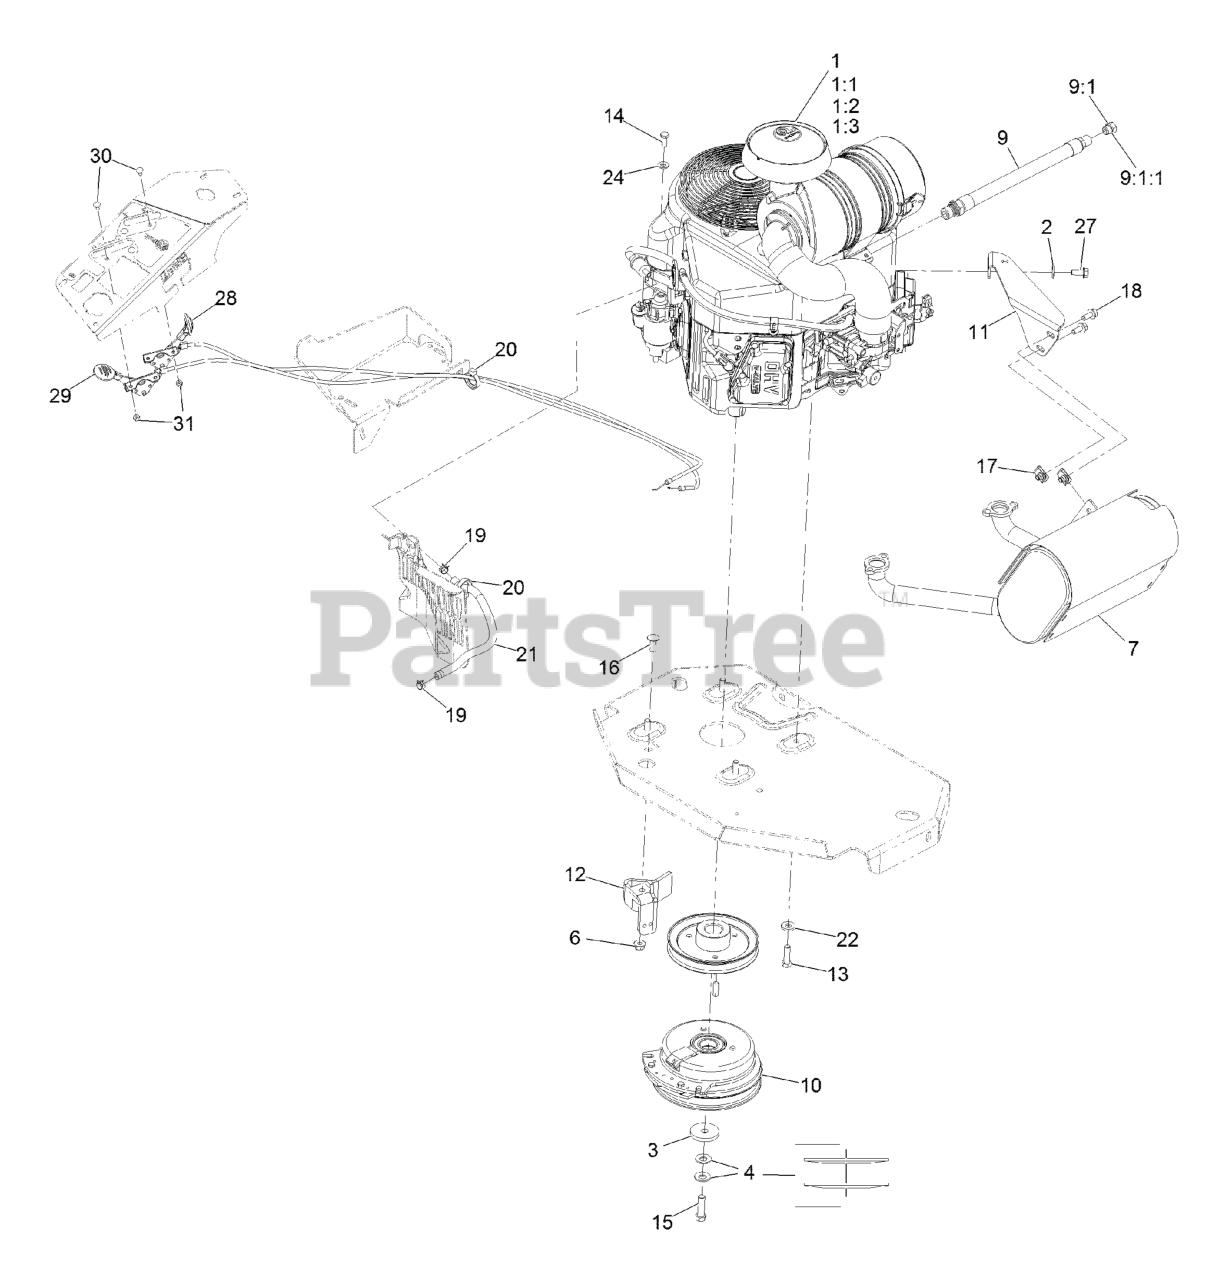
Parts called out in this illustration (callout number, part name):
1:1	Kawasaki 49065-7007 Engine Oil Filter
1:2	Kawasaki 11013-7044 Engine Air Filter
1:3	Kawasaki 11013-7045 Safety Filter
2	WASHER-SPRING
3	WASHER-CLUTCH
4	WASHER-SPRING
6	NUT-HF, NI
7	MUFFLER
9	ENGINE OIL DRAIN HOSE ASM
9:1	PLUG-HH
9:1:1	O-RING
10	CLUTCH KIT
11	BRACKET-MUFFLER
12	CLUTCH-ANCHOR
13	SCREW-HH
14	SCREW-HH
15	SCREW-HH 7/16-20 X 1 1/2 W/LOCTITE
16	SCREW-CARR
18	SCREW-HHF
19	CLAMP-HOSE
20	CLAMP-HOSE
21	HOSE-FUEL
22	WASHER-BELLEVILLE
24	WASHER-PLAIN
27	SCREW-HHF
28	ASM, CHOKE CABLE
29	ASM,THROTTLE CABLE
30	BOLT-CARR
31	NUT-LOCK, NI
